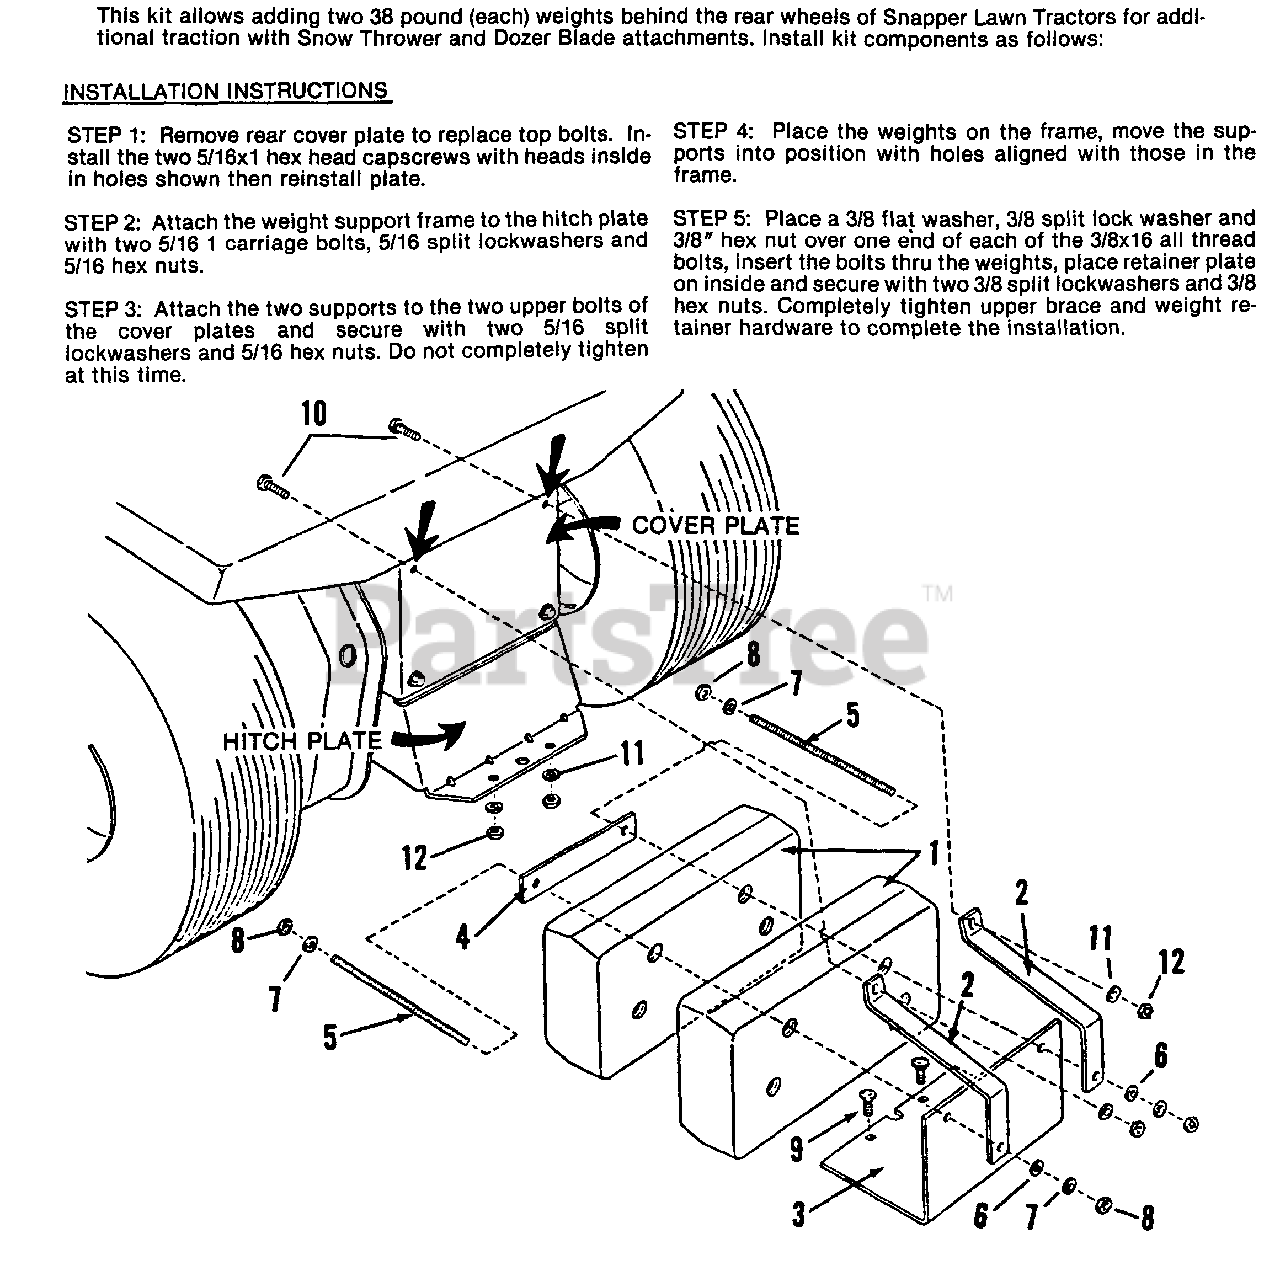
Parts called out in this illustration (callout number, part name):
1	WEIGHT, 38 Pound
2	SUPPORT
4	PLATE, Retainer
5	STUD, 3/8-16 x 9"
6	WASHER, 3/8" Flat
7	WASHER, 3/8 Split Lock
8	NUT, 3/8-16 Hex
9	BOLT, 5/16-18 x 1" Square Neck Carriage
10	SCREW, 5/16-18 x 1" Hex Head Cap, Grade 2
11	WASHER, 5/16 Split Lock
12	NUT, 5/16-18 Hex
